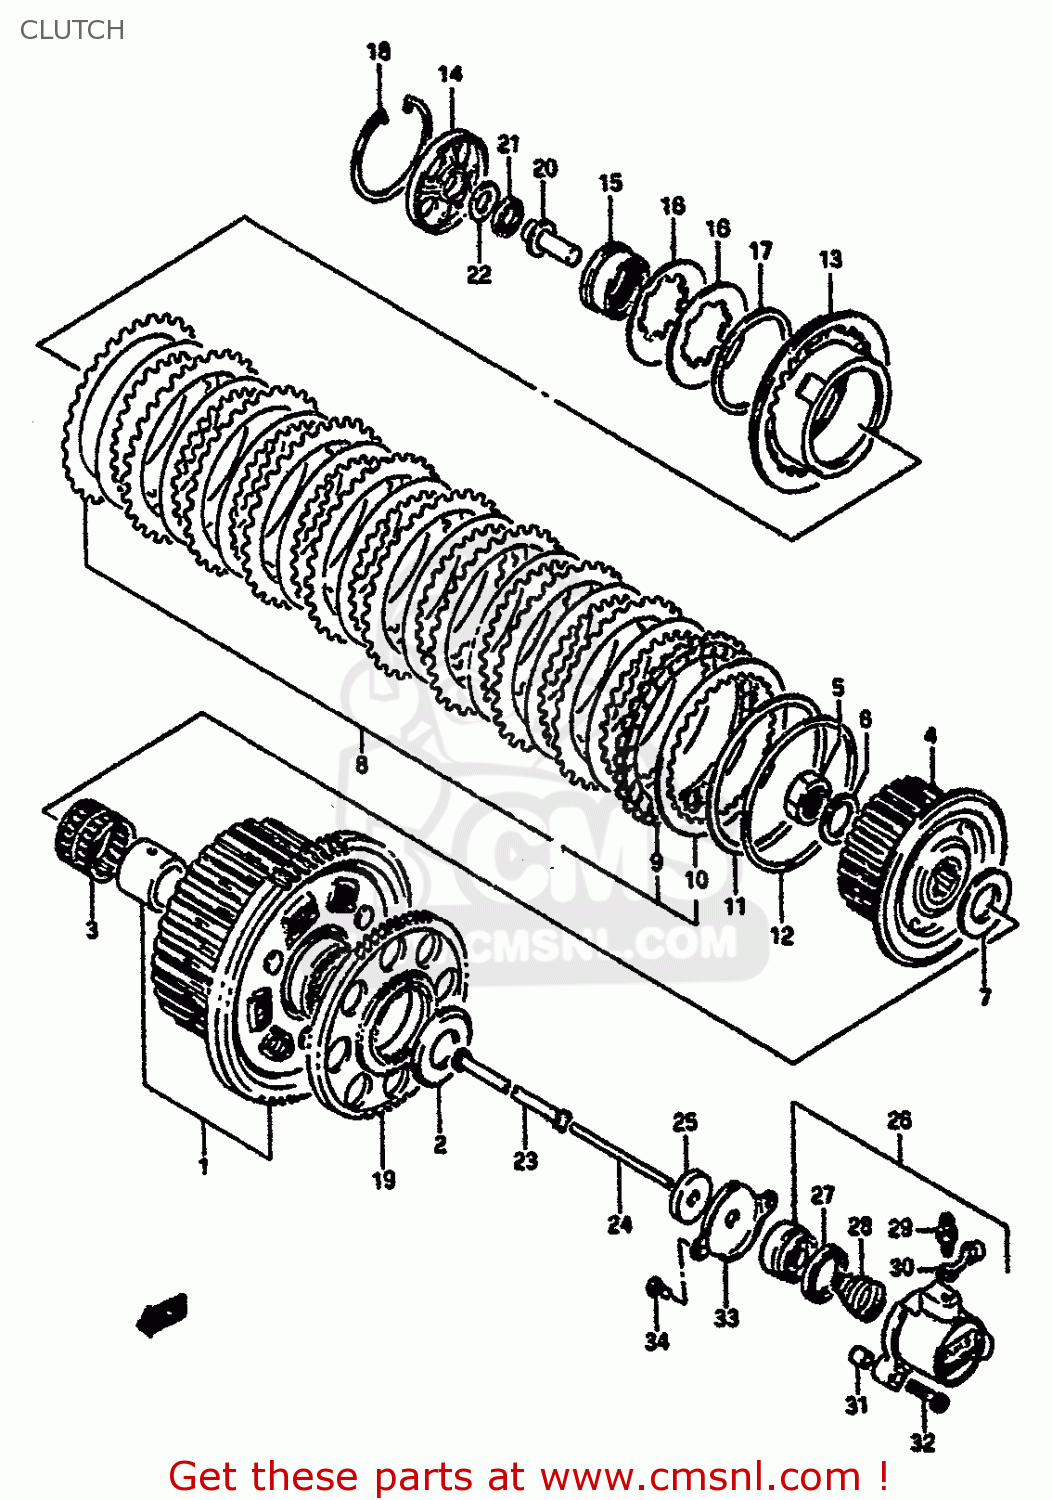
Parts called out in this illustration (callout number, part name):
1	GEAR ASSEMBLY,PRIMARY DRIVE
2	WASHER(25X54X2.5)
3	BEARING(35X40X35.8)
4	HUB,CLUTCH SLEEVE
5	NUT
6	WASHER
7	WASHER(25X50X2.5)
8	PLATE ASSEMBLY,CLUTCH
9	PLATE,CLUTCH DRIVE NO.1 (NAS)
10	PLATE,CLUTCH DRIVEN (NAS)
11	WASHER
12	SEAT,CL SLEEVE HUB WAVE WASHER
13	DISC,CLUTCH PRESSURE
14	LIFTER,CLUTCH PRESSURE DISC
15	HOLDER,CLUTCH SPRING
16	WASHER
17	SEAT,CLUTCH SPRING
18	CIRCLIP
19	GEAR,GENERATOR DRIVE
20	PIECE,CLUTCH PUSH
21	BEARING(15X28X2)
22	WASHER
23	ROD,CLUTCH
24	ROD,CLUTCH PUSH
25	SEAL,OIL(6X34X5.5)
26	CYLINDER,CLUTCH RELEASE
27	CUP
28	SPRING,CLUTCH CYLINDER
29	BLEEDER
30	CAP,BLEEDER
31	PIN
32	BOLT
33	PLATE,CLUTCH PUSH ROD
34	SCREW
